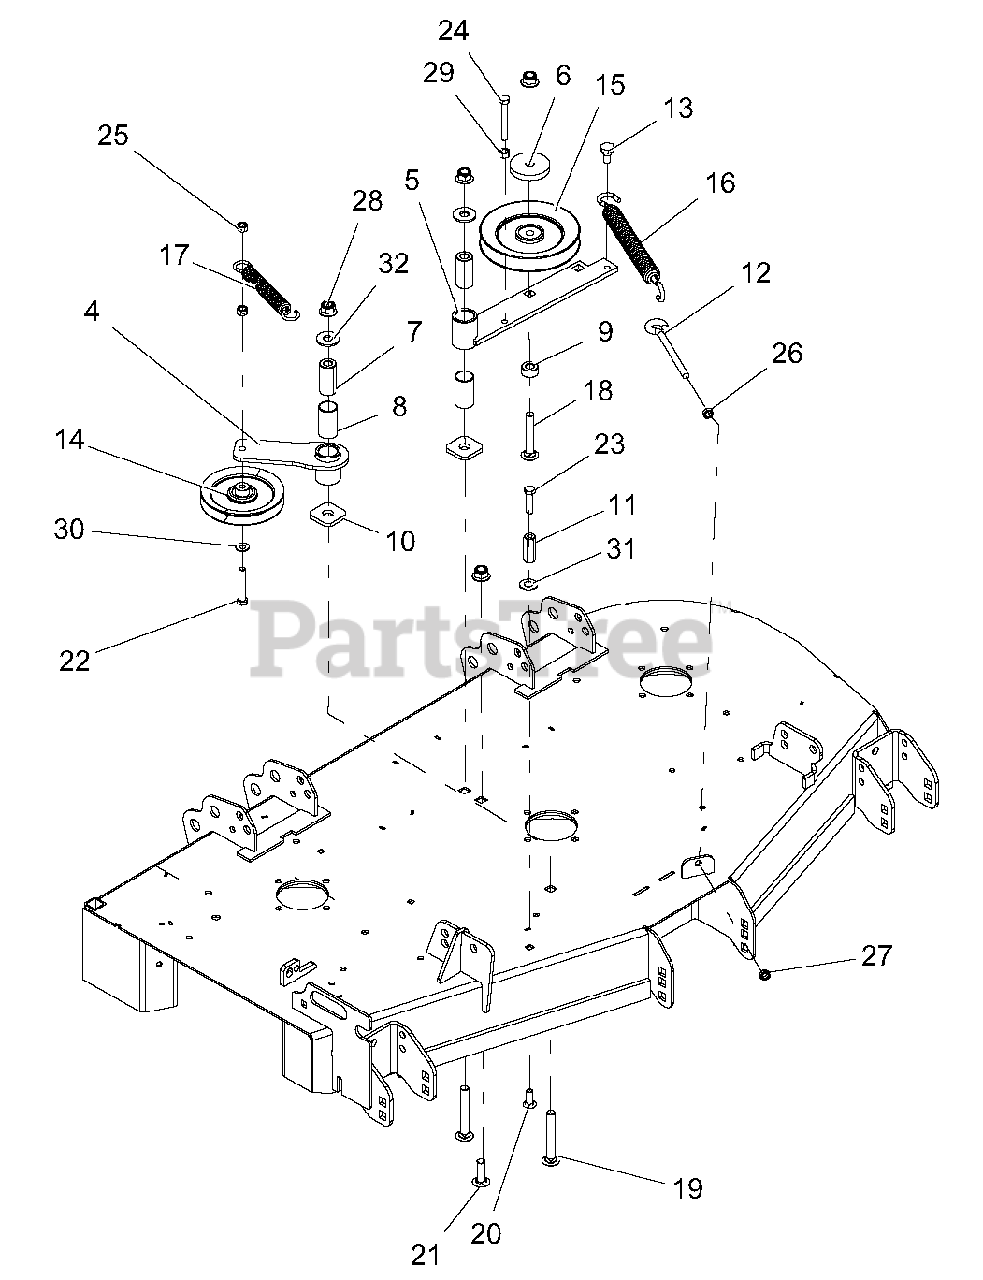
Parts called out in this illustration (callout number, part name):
4	WMT, IDLER PIVOT ARM-BLACK
5	WMT, IDLER PIVOT ARM-BLACK
6	CAP, IDLER BEARING SEALING
7	BSHG, SPCR .502X.997X2.03
8	BSHG, 1.00X1.125X1.937
9	BSHG, SPCR .502 X .997.50 PM
10	WSHR, -FLT.640X1.75X.250
11	NUT-HEX COUPLING
12	BOLT, .38-16 X 4.00 .62 DIAMETER EYE
13	BLT, SHLDR EP .38-16X.30 HEX YZ
14	SHV, .38" ID X 5.0’’ OD V-IDLER
15	SHEAVE, .50" ID X 6.00" OD V-IDLER
16	SPRG, EXTENSION
17	SPRG, EXTENSION
18	@BLT-RDHDSQNK .50-13X3.00Y G5
19	@BLT-RDHDSQNK .50-13X3.50Y G5
20	@BLT-RDHDSHSQNK.38-16X1.0 G5YZ
21	BLT-RDHDSQSHNK .50-13X1.50 YWZC
22	BLT-HEX .38-16X2.25 GR5 YWZC
23	BLT-HEX .38-16X1.50 GR5 YWZC
24	BLT-HEX .38-16X2.75 GR5 YWZC
25	@NUT-LK-CTR .38-16 YWZC
26	NUT, JAM .375-16 YWZC
27	@NUT-LK-CTR-JAM .375-16 YWZC
28	NUT-LK-NYL-FLG .50-13 YWZC
29	NUT-HEX .38-16 YWZC
30	@WSHR-FL-STL.406X.812X.065 YWZ
31	@WSHR-FL-STL.531X1.06X.095YWZC
32	@WSHR-FL-STL.563X1.38X.109YWZC
